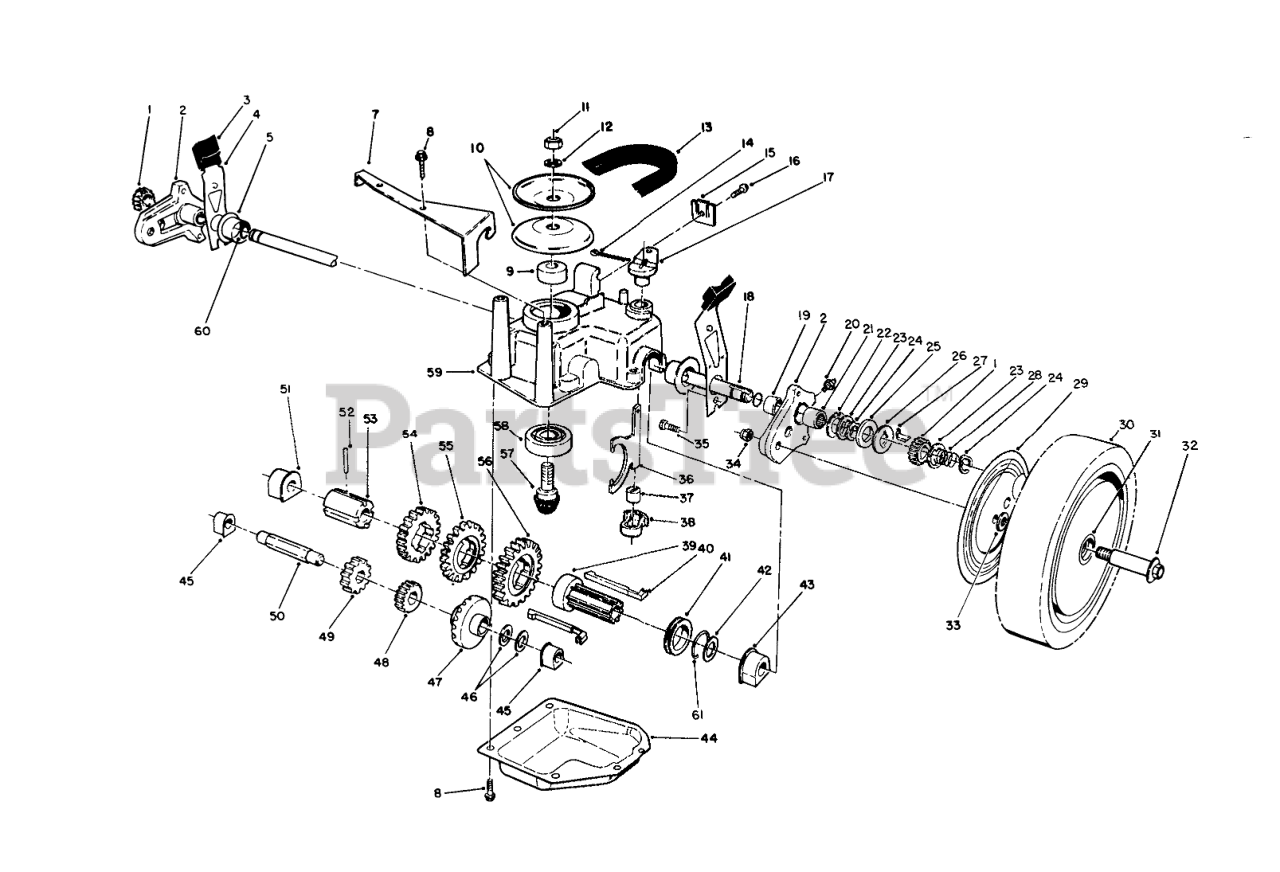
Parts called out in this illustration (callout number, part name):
1	GEAR-PINION
2	Pivot Arm Assembly (Incl. Ref #19, 20, & 21)
3	KNOB-ARM
4	SPRING ARM ASM SP
5	CAP-END
7	Bracket-Guide
8	SCREW-HWHTF
9	SPACER
10	Pulley Half
11	NUT-HEX
12	WASHER-FLAT
13	V-BELT E
14	PIN-COTTER
15	Cable Clamp
16	SCREW-HWHTF
17	SHIFT LEVER
18	SHAFT-OUTPUT
19	BUSHING
20	FITTING-GREASE
21	BEARING-ROLLER
22	WASHER-ARM, PIVOT
23	WASHER-THRUST, KEYED
24	RING-CLIP, LOCKING
25	RING-FRICTION
26	WASHER-CLUTCH
27	KEY-ROCKING, LH
28	SPRING-COMPRESSION
29	WHEEL COVER
30	Wheel-Tire & Gear Ass-y (Incl. Ref. # 31)
31	BUSHING
32	WHEEL BOLT
33	WASHER
34	Nut
35	SCREW-HWH
36	YOKE-SHIFT
37	BUSHING-YOKE
38	RETAINER-FORK, SHIFT
39	SHIFT KEY SLEEVE
40	SHIFT KEY
41	SHIFT COLLAR
42	WASHER-PLAIN
43	BUSHING-OUTPUT
44	Cover-Gearcase
45	BUSHING
46	WASHER-THRUST
47	Gear-Bevel
48	PINION-20T
49	PINION-25T
50	SHAFT-INTERMEDIATE
51	BUSHING
52	PIN-SPRING
53	SLEEVE-GEAR
54	GEAR-39T
55	GEAR-44T
56	GEAR-49T
57	Gear-Pinion
58	BEARING-BALL
59	CASE-GEAR, UPPER
60	O-RING
61	CLIP-SPRING
